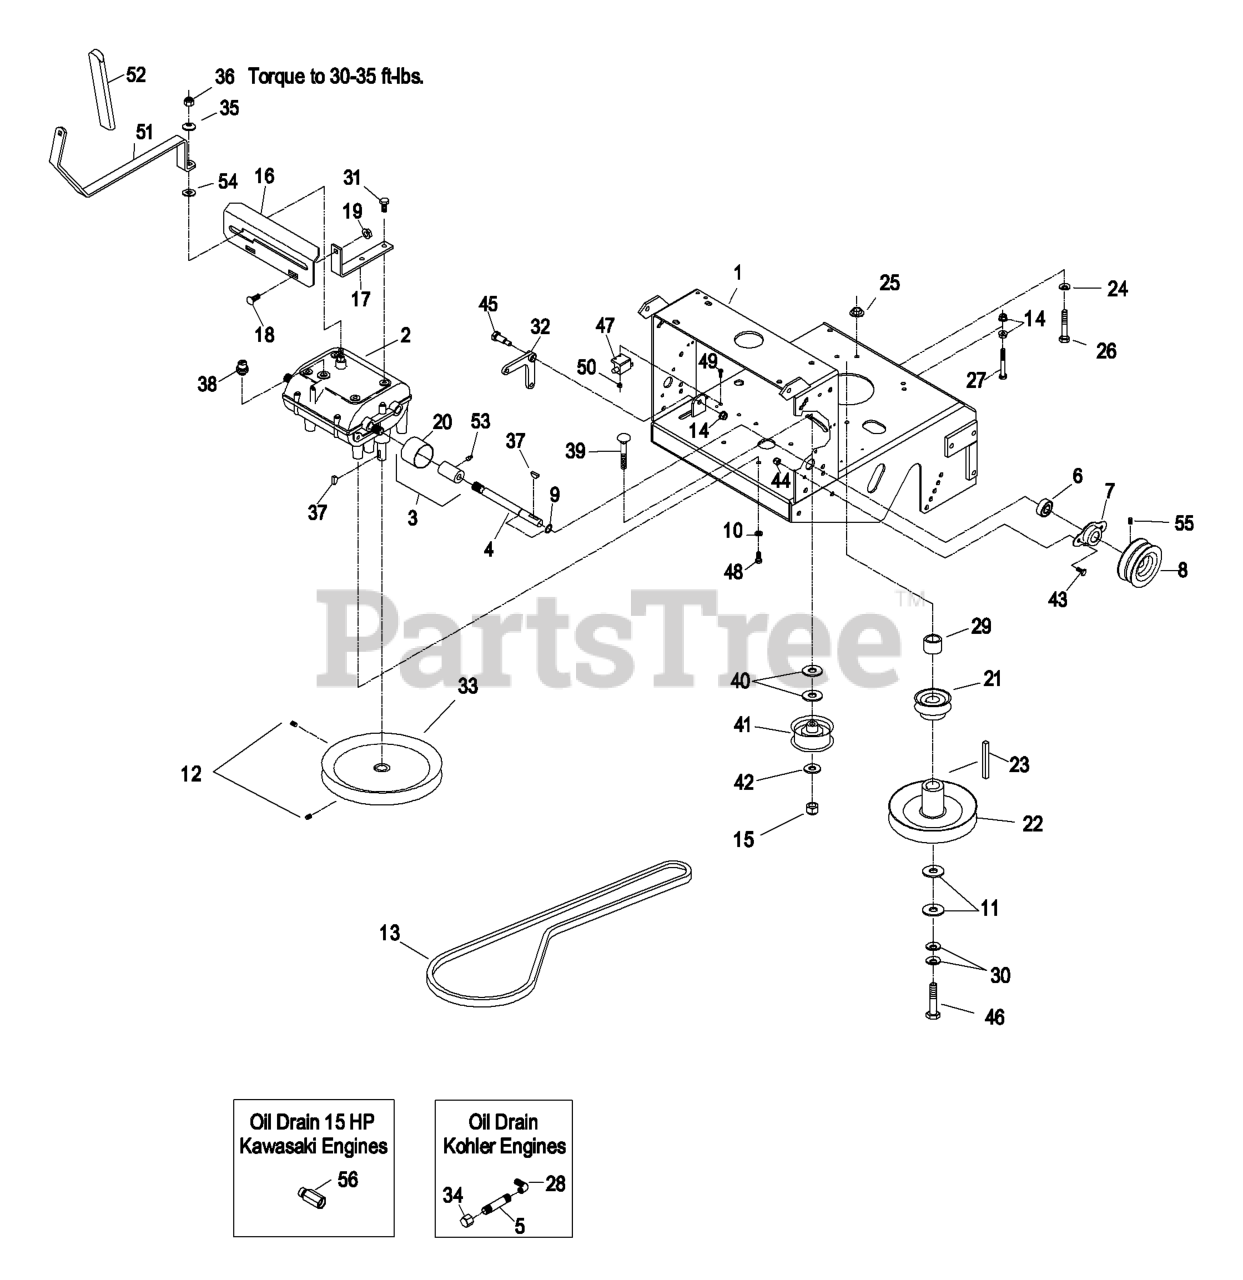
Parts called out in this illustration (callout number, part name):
1	FRAME-DECK, REAR
3	ASM,COUPLER/ZERK
4	SHAFT-TRANSMISSION
5	NIPPLE
6	BEARING-SHAFT
7	FLANGE-OUTPUT
9	RING-RETAINING
10	WASHER-LOCK
12	SCREW-HSH
13	BELT,TRANS DRIVE
14	NUT-HHF, WHIZ
15	NUT-LOCK, NI
17	BRACKET-PLATE, SHIFT
18	BOLT-CARR
20	GUARD-COUPLER
21	SHEAVE-TRANSMISSION
23	KEY-SQUARE
24	WASHER-SPRING
26	SCREW-HH
27	SCREW-HH
28	FITTING-ELBOW-90
29	SPACER-CLUTCH
30	WASHER-SPRING
31	SCREW-HWH, THREAD CUT
32	BELLCRANK
33	SHEAVE-TRANSMISSION
34	CAP-HEX
35	WASHER-BELLEVILLE
36	NUT-LOCK
37	KEY-WOODRUFF
38	SWITCH-START, NEUTRAL
39	SCREW-HH
40	WASHER-FLAT
42	WASHER-FLAT
43	SCREW-HH
44	NUT-LOCK, NI
45	BOLT-SHOULDER
46	SCREW-HH
47	SWITCH-OPEN, NORMALLY
48	SCREW-HH
49	SCREW-PPH
50	NUT-LOCK, NI
51	ASM,SHIFT LEVER
52	GRIP,FOAM
53	FITTING-GREASE
55	SCREW-SET
56	ADAPTER
